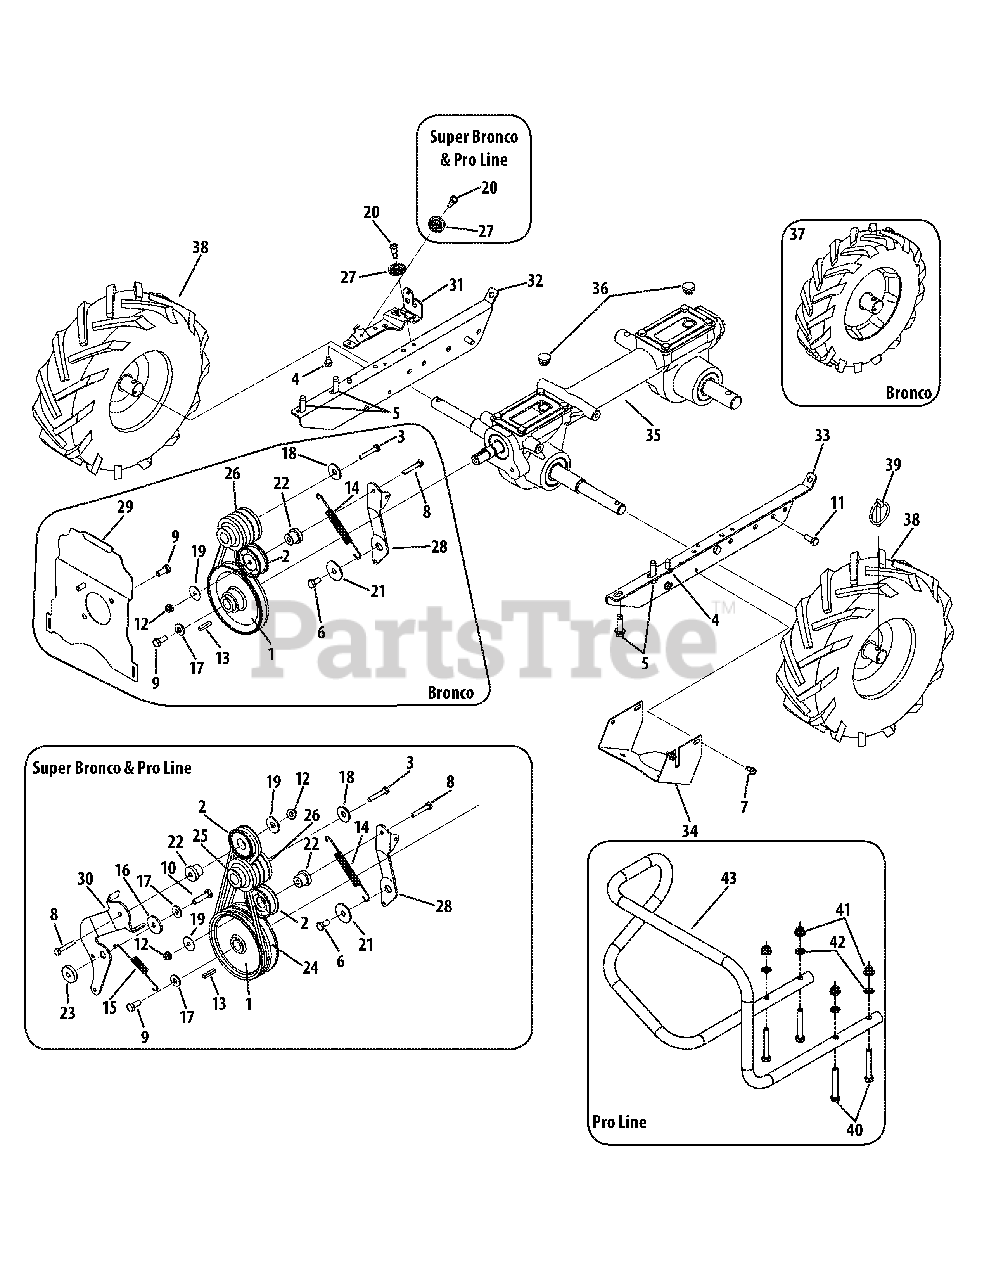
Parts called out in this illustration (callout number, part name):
1	Engine Pulley
2	Idler Pulley Assembly
3	Hex Screw,3/8 -24 x 2
4	Screw, 5/16-18 x .750
5	Screw, 3/8 -16 x 1.250
6	Hex Screw, 5/16-18 x .625
7	Screw, 1/4-20 x .500
8	Hex Screw, 1/4-20 x 1.50
9	Hex Screw,5/16-24 x .750
10	Hex Screw, 5/16-24 x 1.250
11	Hex Screw, 5/16-18 x .75
12	Flange Lock Nut, 1/4-20
13	Key, 3/16 x 1.00
14	Extension Spring, .480 x 5.00
15	Extension Spring
16	Flat Washer, .330 x 1.25 x .120
17	Belleville Washer, .827 x .331 x .098
18	Belleville Washer, .396 x 1.140 x .095
19	Flat Washer, .265 x 1.0 x .030
20	Shoulder Screw, 1/4-28 x .340 x .335
21	Pivot Spacer
22	Shoulder Spacer, .260 x .785 x .538
23	Pivot Spacer
24	Forward Drive Belt, 4 x 25.375
25	Reverse Drive Belt, 3 x 29.125
26	Engine Pulley
27	Cable Roller
28	Forward Idler Bracket
30	Reverse Idler Bracket
35	Transmission Assembly
36	Rubber Oil Plug
37	Wheel, 11 x 4-4
38	Wheel, 13 x 5 x 6
39	Klik Pin
40	Hex Screw, 5/16-18 x 2.25
41	Flange Lock Nut, 5/16-18
42	Speed Nut, .3125
